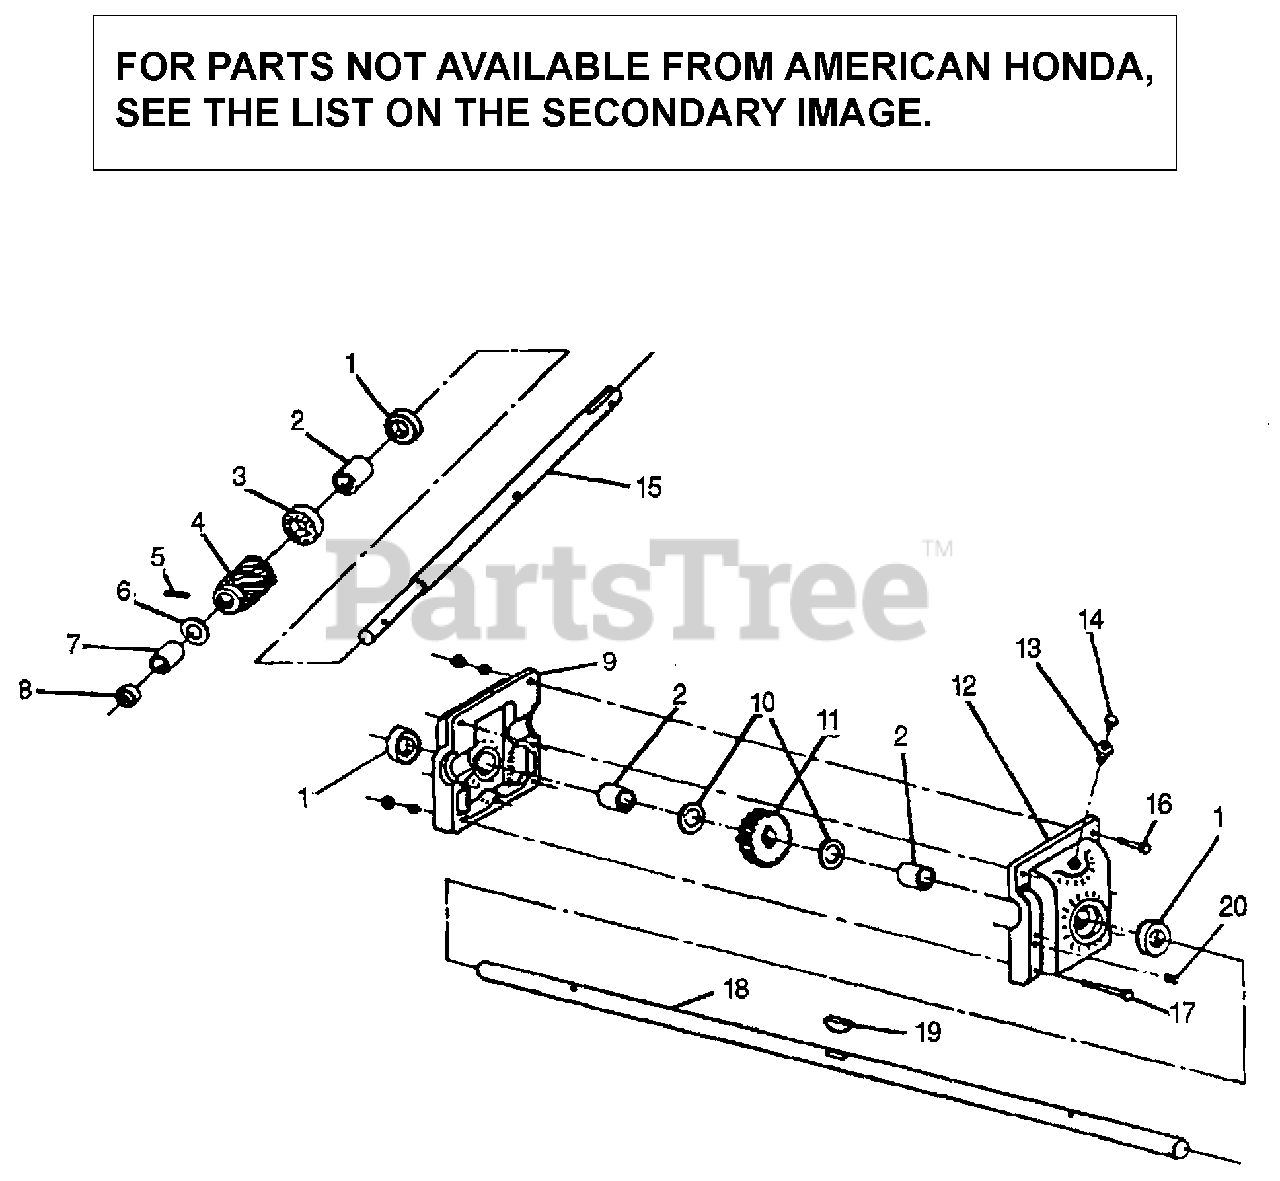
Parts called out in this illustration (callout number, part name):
1	OIL SEAL (GR 9818)
2	BUSHING (1X1-1/4")
3	BEARING (SKF 51105)
4	WORM, RH ROTATION
5	PIN (1/4X1-1/2")
6	WASHER (1-3/8")
7	BUSHING (7/8X1-1/8")
8	CAP, INPUT
9	COVER, R.
10	WASHER (1-1/2")
11	GEAR, BRASS CLOCKWISE (#65)
12	COVER, L.
13	COUPLING (3/8X1/8")
14	BREATHER (1/8" NPT)
15	SHAFT, INPUT
18	SHAFT
19	KEY, WOODRUFF
20	PLUG, LEVEL NPT (1/8")
